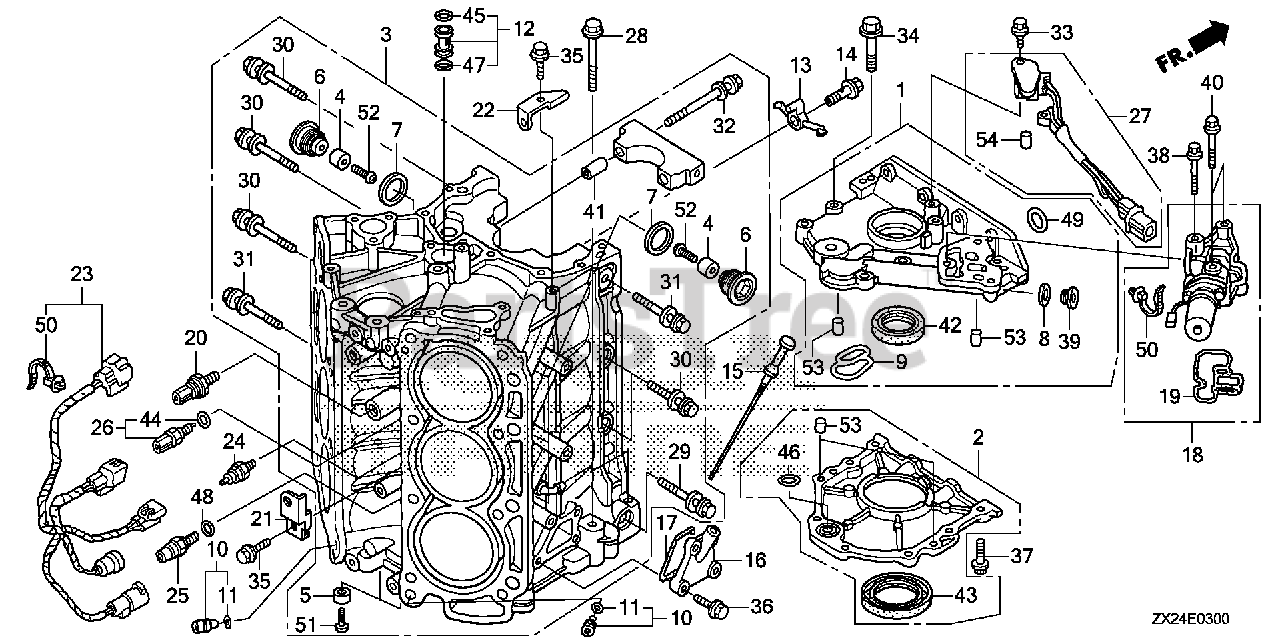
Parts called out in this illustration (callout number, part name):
1	COVER ASSY., CRANKCASE (UPPER) *NH8* (DARK GRAY)
2	CASE ASSY., OIL SEAL
3	BLOCK ASSY., CYLINDER *NH8* (DARK GRAY)
4	METAL, ANODE
5	METAL, ANODE
6	BOLT, SEALING (22MM)
7	WASHER, SEALING (22MM)
8	WASHER, SEALING (22MM)
9	GASKET, OIL HOLE
10	ORIFICE ASSY., OIL CONTROL
11	O-RING (8.8X2.4)
12	JOINT ASSY., OIL PIPE
13	BODY, OIL JET
14	BOLT, OIL JET
15	DIPSTICK, OIL
16	COVER, OIL LEVEL GAUGE
17	GASKET, OIL LEVEL GAUGE
18	VALVE ASSY., SPOOL *NH8* (DARK GRAY)
19	FILTER ASSY., SPOOL VALVE
20	SENSOR, KNOCK
21	BRACKET, CLIP B
22	BRACKET B, HARNESS CLIP
23	WIRE, SWITCH
24	SWITCH ASSY., OIL PRESSURE
25	SWITCH ASSY., OIL PRESSURE
26	SENSOR ASSY., WATER TEMPERATURE
27	SENSOR ASSY., CRANK
28	BOLT, FLANGE (12X95)
29	BOLT-WASHER (10X109)
30	BOLT-WASHER (10X60)
31	BOLT-WASHER (10X80)
32	BOLT-WASHER (11X105)
33	BOLT, FLANGE (6X16)
34	BOLT, FLANGE (6X35)
35	BOLT, FLANGE (6X14)
36	BOLT, FLANGE (6X18)
37	BOLT, FLANGE (6X22)
38	BOLT, FLANGE (8X75)
39	BOLT, SEALING (22MM)
40	BOLT, FLANGE (8X50)
41	PIN, DOWEL (13X37)
42	OIL SEAL (41X66X8)
43	OIL SEAL (80X98X10) (ARAI)
44	O-RING (9.5X1.9)
45	O-RING (18.3X3.5)
46	O-RING (26.2X2.4) (YAMADA SOMBOON)
47	O-RING (16.3X3.5)
48	O-RING (13X1.5) (ARAI)
49	O-RING (25X2.4) (NOK)
50	CLIP, HARNESS BAND (145MM) (BLACK)
51	SCREW, PAN (5X16)
52	SCREW, PAN (5X20)
53	PIN, DOWEL (6X10)
54	PIN, DOWEL (5X8)
